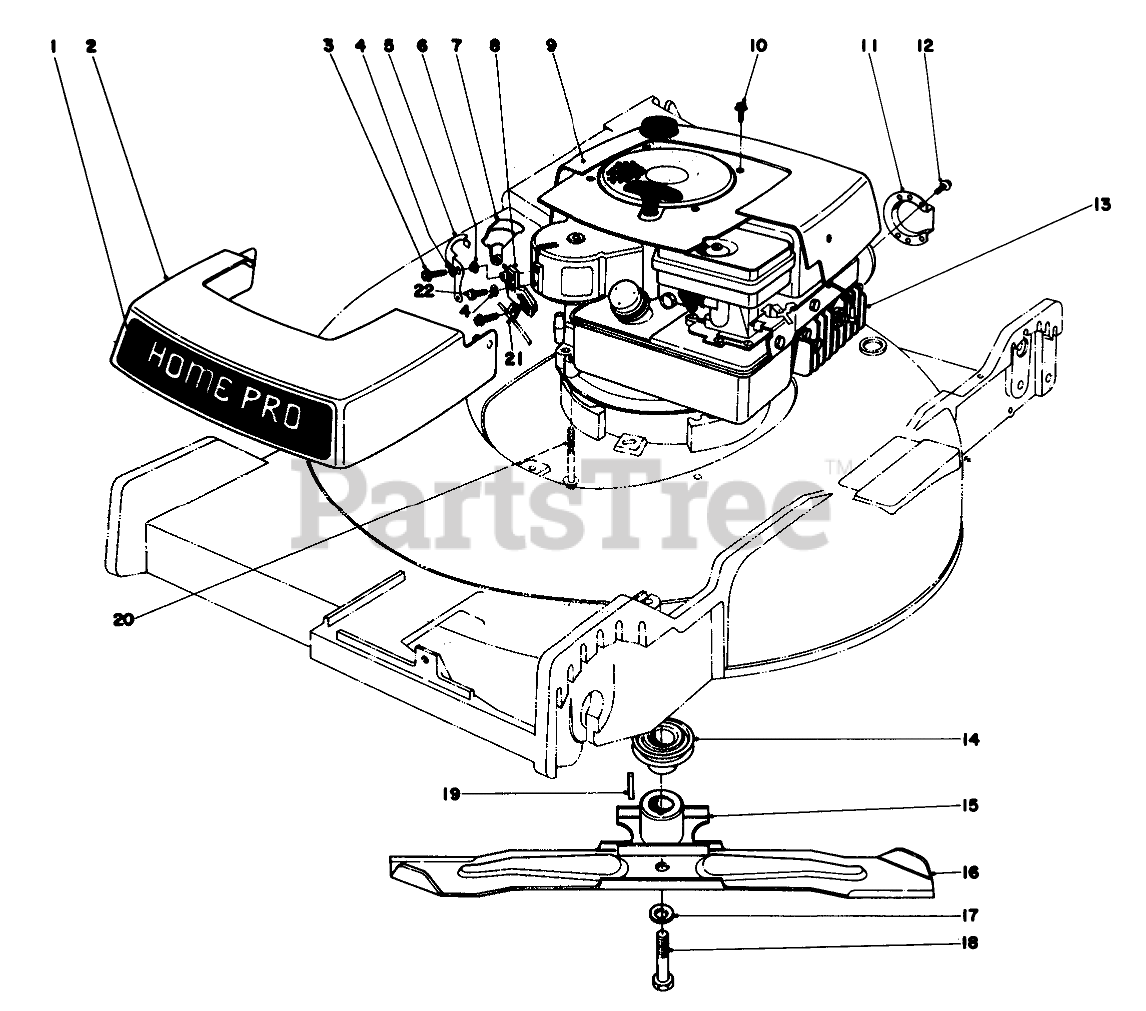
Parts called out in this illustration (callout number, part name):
1	Decal Shroud
2	Shroud Front
3	Screw
4	WASHER-FLAT
5	CAM INTERLOCK
6	BUSHING
7	INTERLOCK LEVER
8	CABLE & PIVOT BLOCK
9	Shroud Rear
10	8X1/2 SELF TAP SCREW
11	Deflector
12	SCREW W/ENGINE
13	Engine
14	DRIVER PULLEY
15	BLADE RETAINER WA(BLACK)
16	Blade
17	WASHER-LOCK
18	BLADE SCREW
19	KEY-SQUARE
20	3/8-16 X 2-3/4 CAPSCR
21	CLAMP
22	SCREW-SHWH
